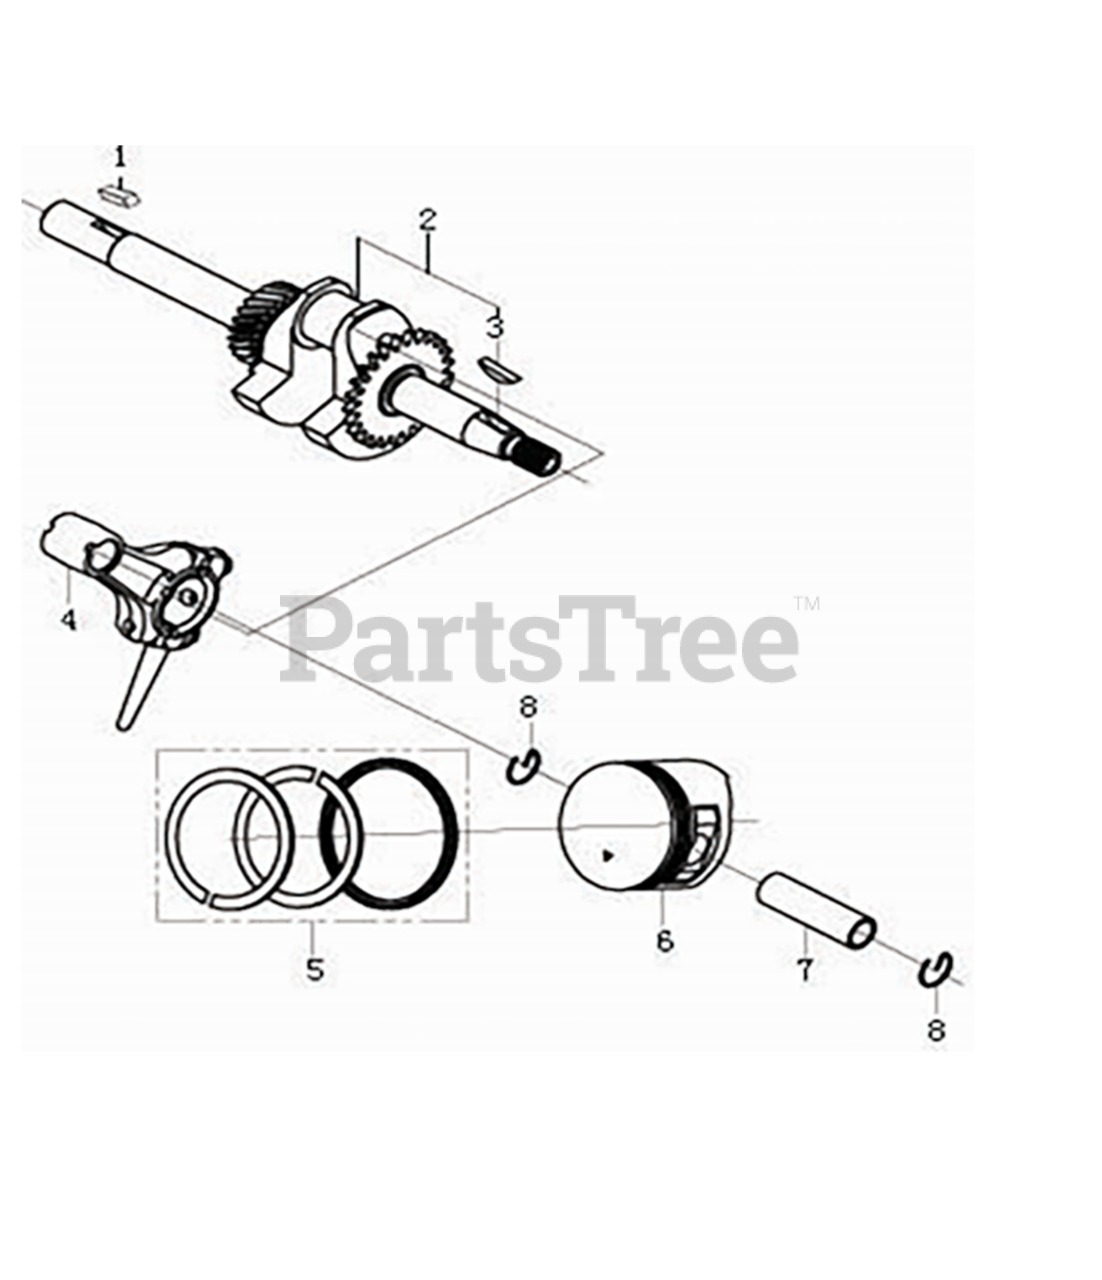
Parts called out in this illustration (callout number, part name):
1	KEY, WDRF .157 X .630
2	crankshaft
4	Connecting rod
5	Piston ring combination
6	Piston
7	Piston pin
8	Steel cable baffle ring
